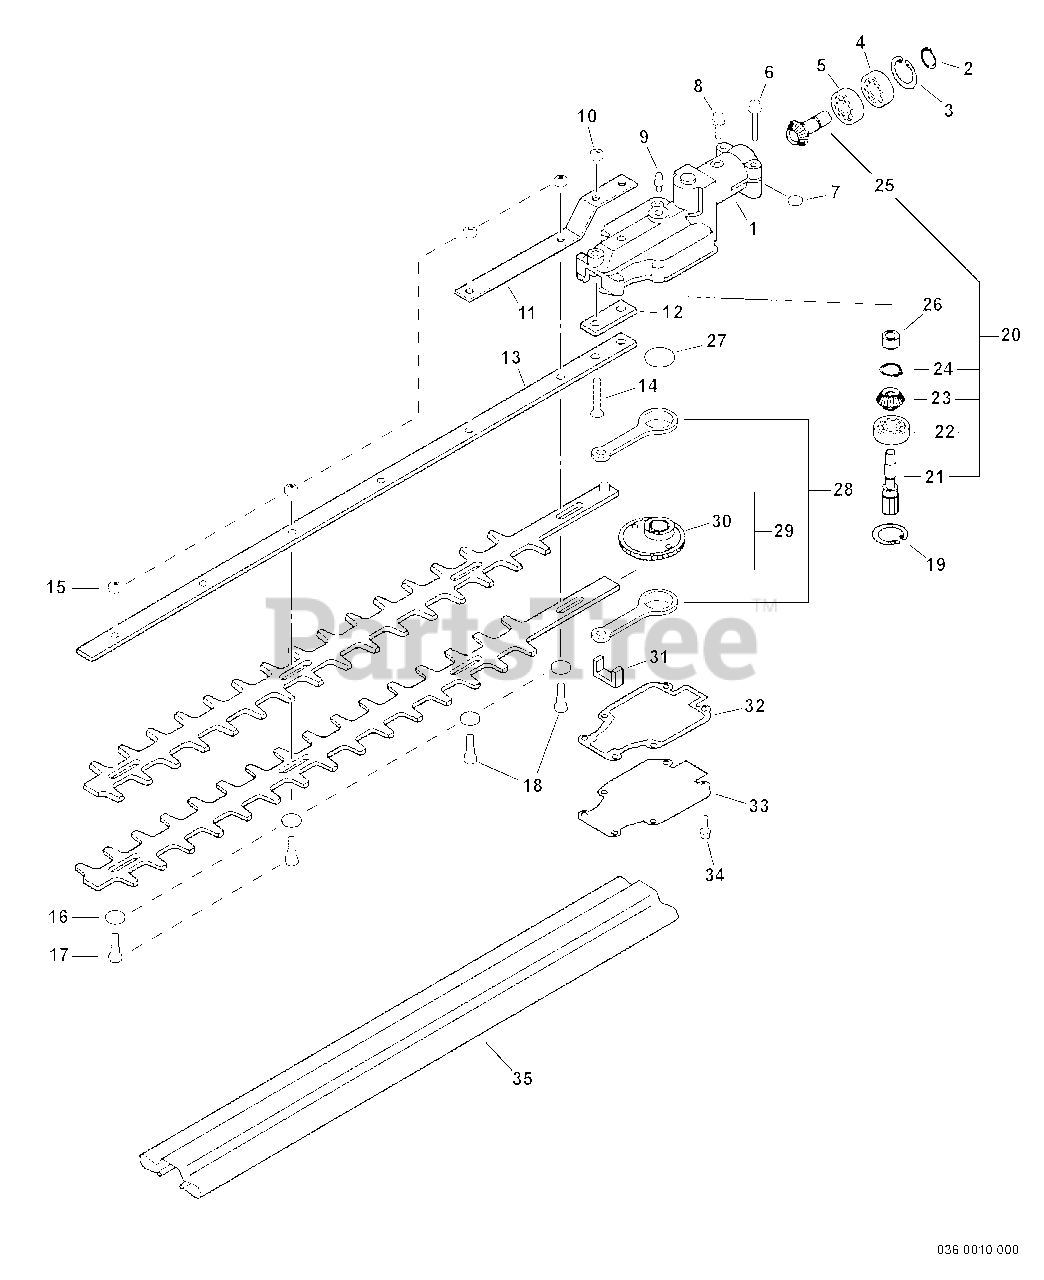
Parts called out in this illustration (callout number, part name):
1	CASE, GEAR
2	RING, RETAINING - 12
3	RING, RETAINING - 24
4	BEARING, BALL - 6901Z
5	BEARING, BALL - 6901
6	SCREW - 5X28
8	SCREW - 5X12
9	FITTING, GREASE
10	LOCKNUT - 6
13	SUPPORT, BLADE
14	SCREW - 6X35
15	LOCKNUT - 6
16	WASHER - 6
17	BOLT - 6
19	RING, RETAINING - 24
20	SPUR GEAR SET
21	GEAR - SHAFT
22	BEARING, BALL - 6901
23	GEAR - BEVEL
24	RING, RETAINING
25	GEAR - BEVEL
26	BEARING, NEEDLE
28	ROD, CONNECTING
29	BLADE - 20" (50cm)
30	GEAR - DRIVE
31	SEAL, FELT
32	GASKET, GEAR CASE
33	LID, GEAR CASE
34	SCREW - 4X12
35	COVER, BLADE
